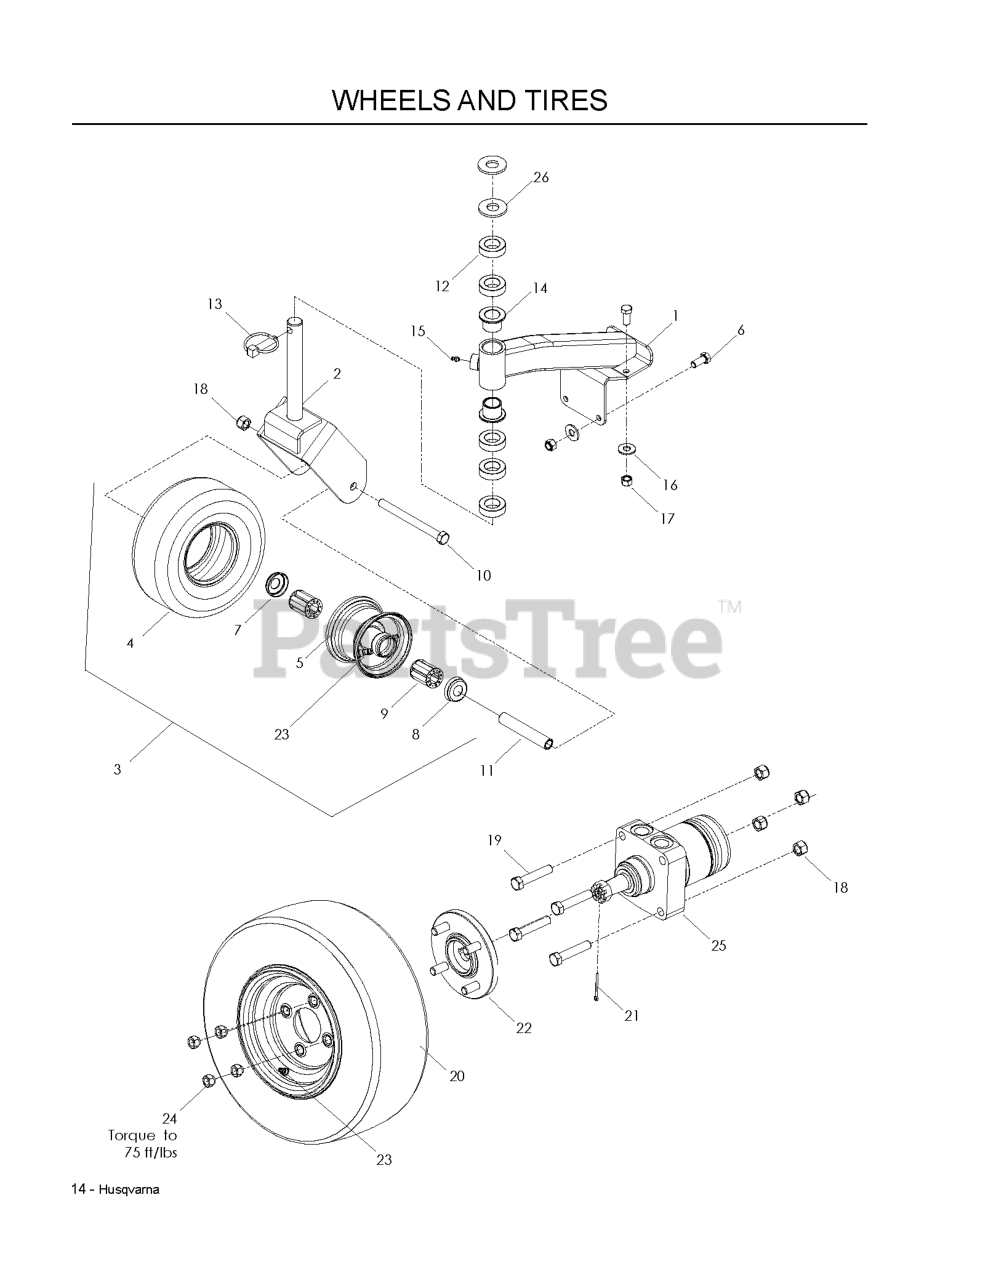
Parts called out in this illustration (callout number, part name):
3	TIRE/WHEEL.CASTER.9X3.5-4.SMOO
4	TIRE 9 X 3.5 - 4
6	HCS 3/8-16 X 7/8 GR 5 ZD
7	ENDCAP
8	ENDCAP, NOTCHED
9	ROLLER BEARING
10	HCS 1/2C X 5 1/2
13	LYNCH PIN 7/16
14	BSHG 1.003X1.252X1.75 LG OIL
15	ZERK
16	WASHER 3/8 FLAT
17	NUT 3/8-16 NYLOC
18	NUT 1/2-13 HEX NYLOC ZD
19	HEX SCREW 1/2-13 X 2.5" GR 5
20	WHEEL ASSY, 16 X 7.5-8 OFFSET
21	COTTER PIN
22	HUB, WHEEL
23	VALVE STEM TR-412
24	LUG NUT 1/2F
25	WHEEL MOTOR
26	SPACER, .25 HEIGHT ADJ
